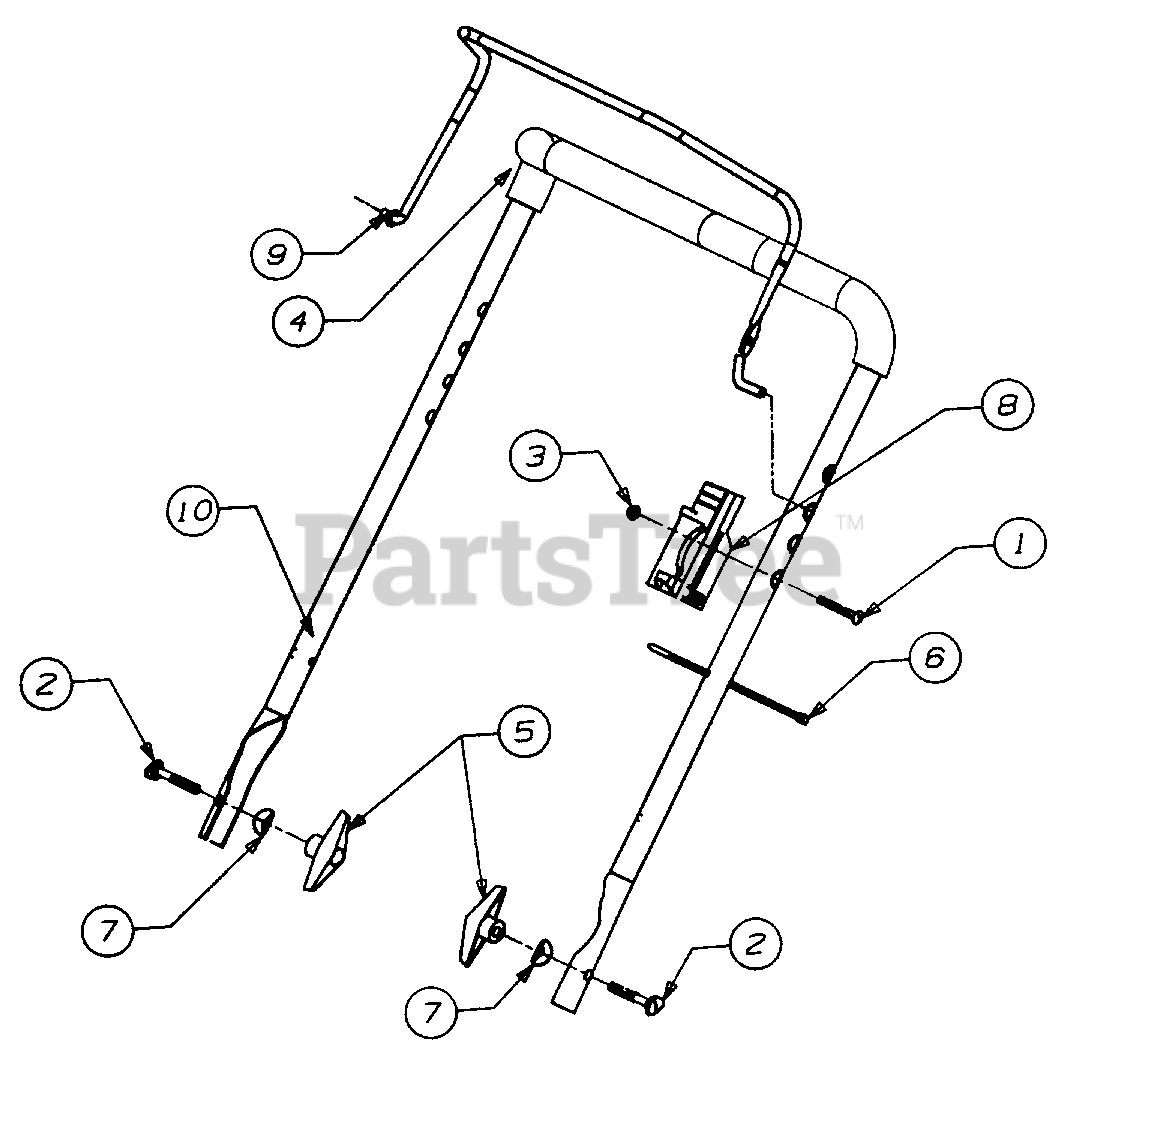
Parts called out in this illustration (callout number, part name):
1	Screw-Oval C-Sink L
2	Bolt-Carriage
3	Nut Insul. Lock
4	Grip Foam
5	Knob Handle
6	Tie Cable
7	Washer Saddle
8	Body-Lever Control
9	Handle Ass'y. Control
